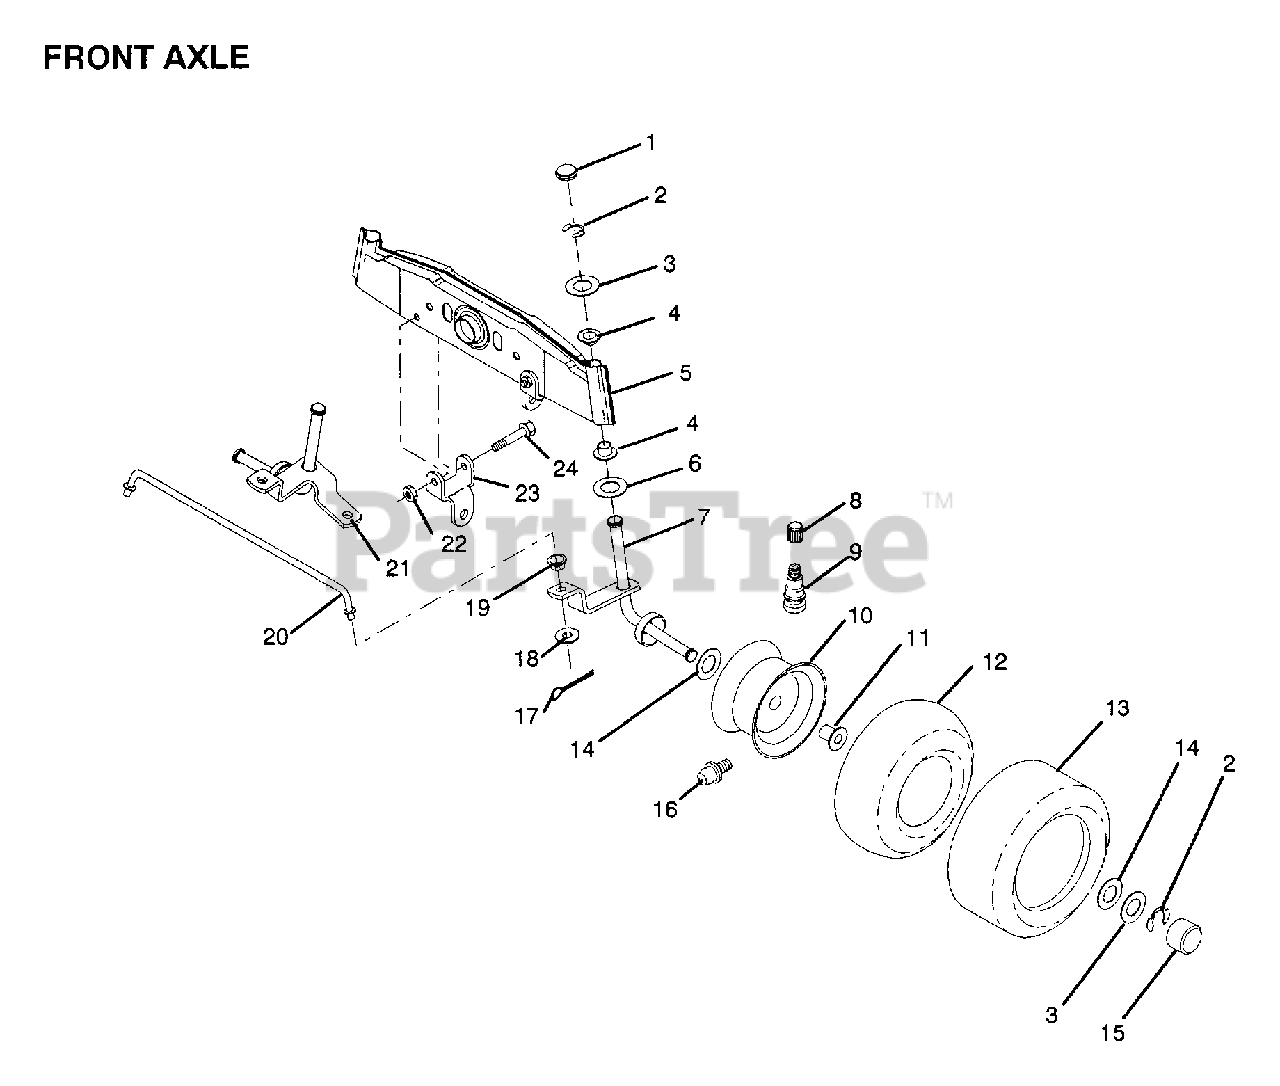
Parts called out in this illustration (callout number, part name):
1	CAP
2	RING
3	WASHER
4	NYLINER
5	AXLE FRONT
6	WASHER .T
7	SPINDLE RH
8	VALVE CAP
9	VALVE STEM LT
11	"FLANGE, BEARING"
12	TUBE.5.3/4.5/6
13	TIRE
14	WASHER
15	HUB CAP
16	FITTING LT
17	COTTER PIN
18	WASHER
19	BUSHING.DRAGLINK
20	ROD TIE
21	SPINDLE LH
23	"BRKT,FRONT STAB"
24	BOLT
